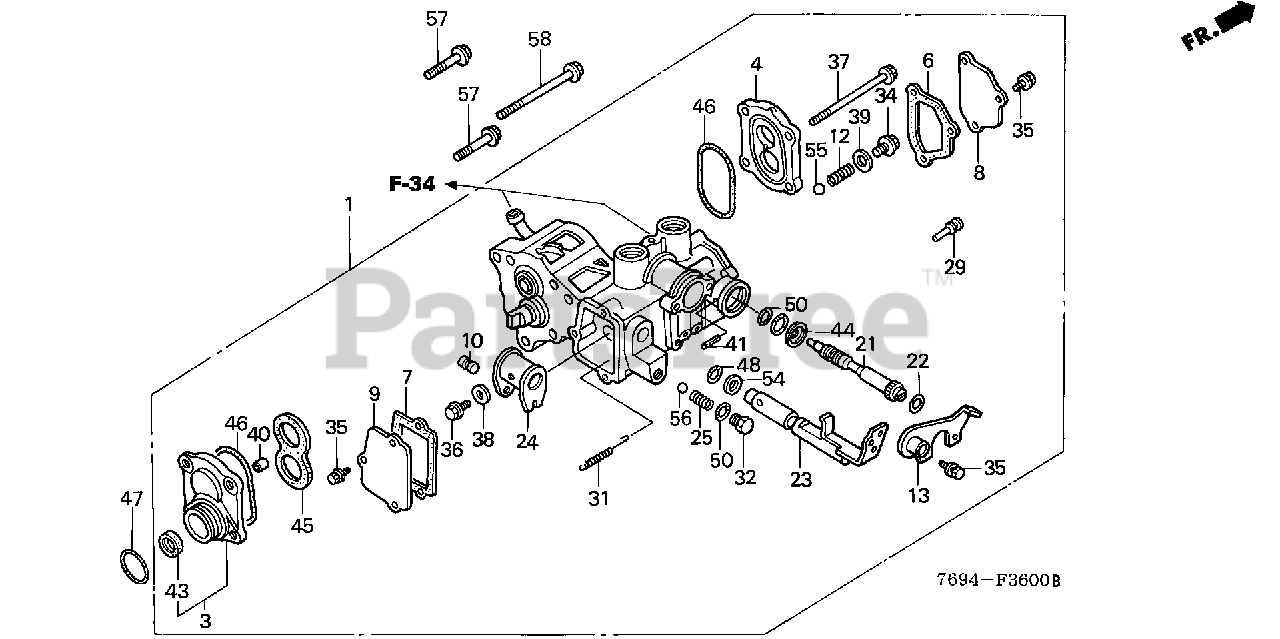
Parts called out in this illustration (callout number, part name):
1	PUMP & VALVE ASSY.
3	COVER, FR. PUMP
4	COVER, RR.
6	GASKET A, VALVE FRAME
7	GASKET B, VALVE FRAME
8	COVER A, VALVE FRAME
9	COVER B, VALVE FRAME
10	PIN, MANUAL VALVE
12	SPRING, ROTARY BALL SET
13	PLATE, ROTARY STOPPER
21	VALVE, DRAIN CONTROL
22	MARK, HYDRAULIC ADJUSTING KNOB (ENGLISH)
23	SHAFT, HYDRAULIC CONTROL
24	FORK, SPOOL VALVE
25	SPRING, BALL SET (A)
31	SPRING, MANUAL VALVE
32	PLUG (10X8.5)
34	BOLT, FLANGE (8X8)
35	BOLT, FLANGE (6X14)
36	BOLT, SPECIAL (6X20)
37	BOLT, FLANGE (6X85)
38	WASHER, CONICAL SPRING (8MM)
39	WASHER, SEAL
40	PIN, DOWEL (8X10)
40	PIN A, DOWEL (8X10)
41	PIN, SPRING (4X20)
43	OIL SEAL (16X30X7) (NOK)
44	DUST SEAL (12X22X4)
45	SEAL, PLUNGER (NOK)
46	O-RING (53.8X3.1)
47	O-RING (37.5X2)
48	O-RING (11.8X2.4)
50	O-RING (7.8X1.9)
54	RING, BACK-UP (12MM)
55	BALL, STEEL (8)
56	BALL, STEEL (11)
57	BOLT, FLANGE (8X35)
58	BOLT, FLANGE (8X75)
